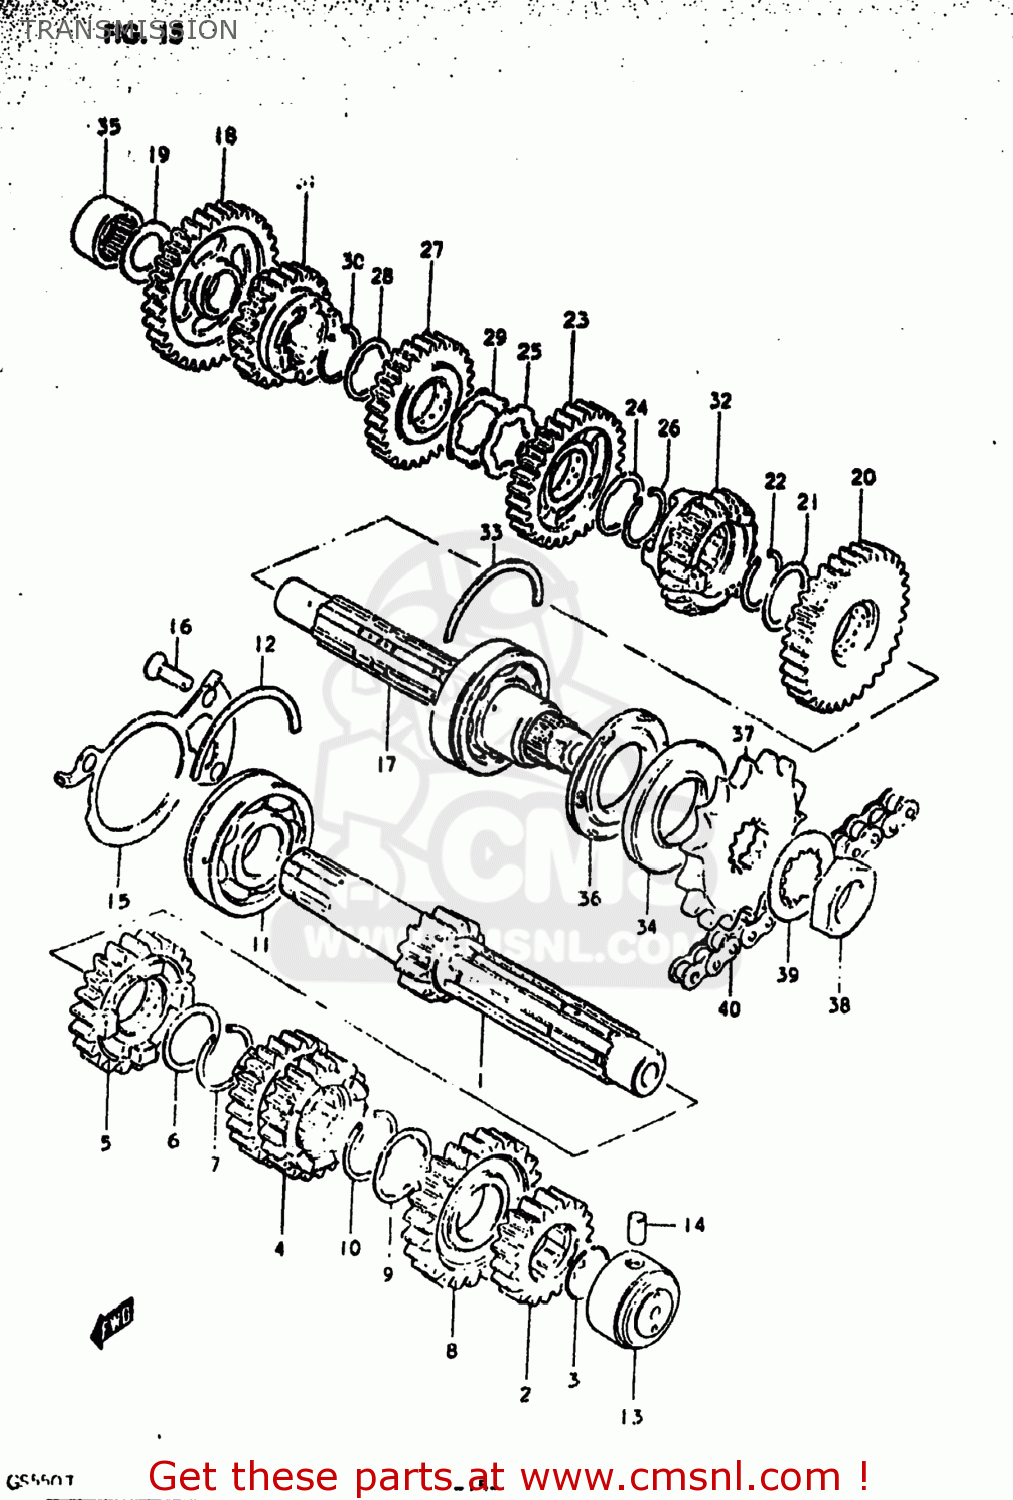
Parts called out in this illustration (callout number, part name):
1	SHAFT,COUNTER
2	GEAR,SECOND DRIVE
3	RING,SNAP
4	GEAR,THIRD DRIVE
5	GEAR,FIFTH DRIVE
6	WASHER
7	CIRCLIP
8	GEAR,SIXTH DRIVE
9	WASHER,LOCK
10	CIRCLIP
11	BEARING(25X62X17)
12	C-RING
13	BEARING
14	PIN
15	PLATE,COUNTERSHAFT BEARING
16	SCREW
17	SHAFT,DRIVE
18	GEAR,FIRST DRIVEN
19	WASHER
20	GEAR,SECOND DRIVEN
21	WASHER
22	CIRCLIP
23	GEAR,THIRD DRIVEN
24	WASHER,LOCK
25	WASHER,LOCK
26	CIRCLIP
27	GEAR,FOURTH DRIVEN
28	WASHER,LOCK
29	WASHER
30	CIRCLIP
31	GEAR,FIFTH DRIVEN
32	GEAR,SIXTH DRIVEN
33	C-RING
34	OIL SEAL
35	ROLLER BEARING (20X34X1
36	SEAL,OIL(32X62X5.5)
37	SPROCKET,ENGINE
38	NUT
39	WASHER
40	CHAIN ASSEMBLY,DRIVE
